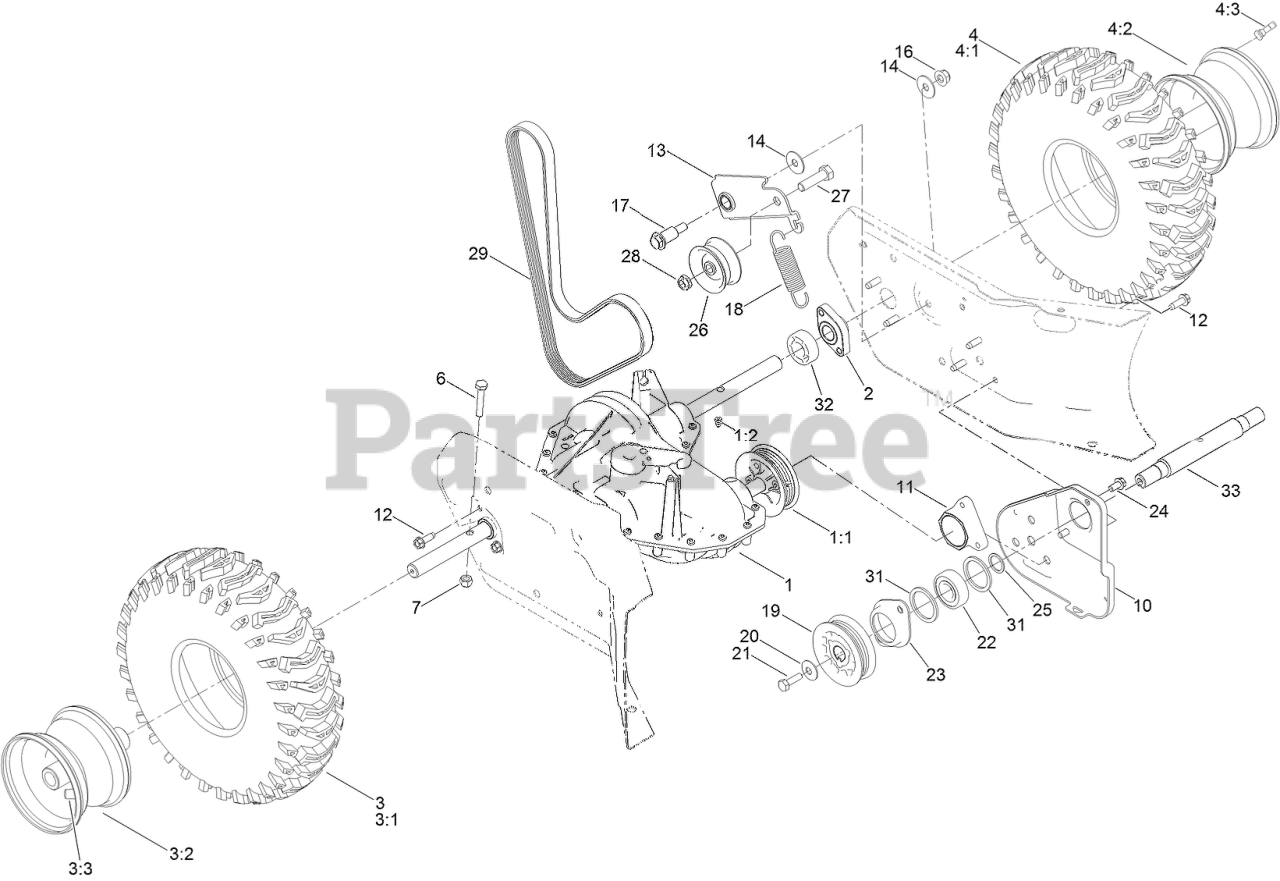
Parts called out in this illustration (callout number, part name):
1	TRANSMISSION
1:1	PULLEY REPAIR KIT
1:2	PLUG-OIL
2	BEARING-AXLE
3	Loose Parts Package
4	Loose Parts Package
6	SCREW-HH
7	NUT-HEX
10	PLATE-SUPPORT, JACKSHAFT
11	SUPPORT-BEARING
12	SCREW-HWHTF
13	IDLER-TRACTION
14	WASHER
16	NUT-HF
17	BOLT-SHOULDER, HHF
18	SPRING-EXTENSION
19	PULLEY-JACKSHAFT
20	WASHER-BELLEVILLE
21	SCREW-HH,LOCK
22	BEARING-BALL
23	RETAINER-BEARING
24	SCREW-HWH
25	WASHER-THRUST
26	PULLEY-IDLER, FLAT
27	SCREW-HH
28	NUT-HEX
29	BELT-POLY V
31	WASHER-RUBBER
32	SPACER-AXLE
33	JACKSHAFT
